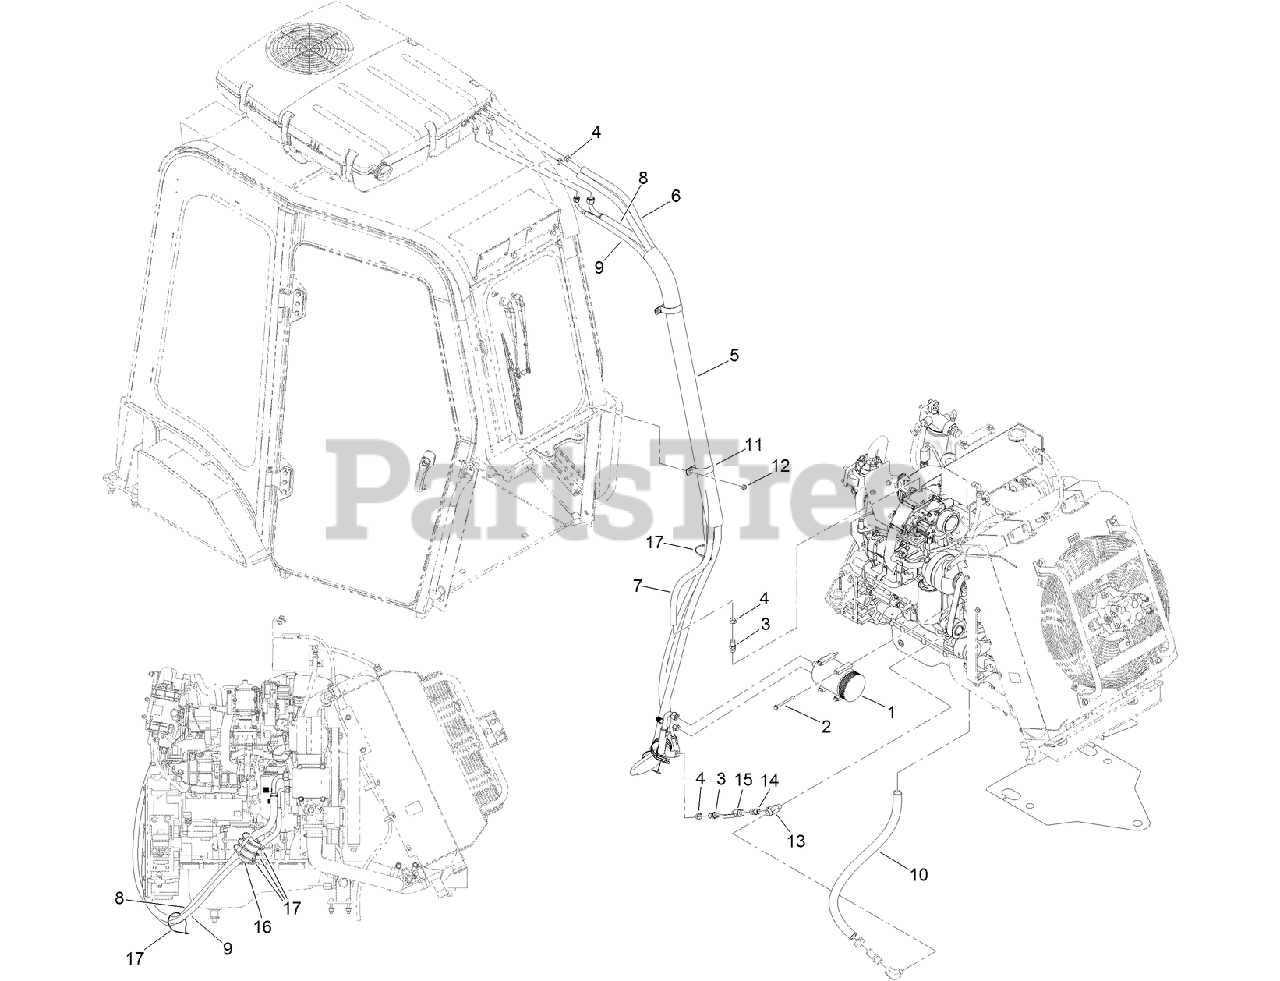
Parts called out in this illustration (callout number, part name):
1	COMPRESSOR-A/C
2	SCREW-HHF
3	FITTING-STRAIGHT
4	CLAMP-DRIVE, WORM
5	SLEEVE-PROTECTIVE
6	HOSE-HEATER
7	HOSE-HEATER
8	HOSE ASM
9	HOSE ASM
10	HOSE-COOLANT
11	CLAMP-SUPPORT
12	NUT-HF, NI
13	FITTING-TEE
14	COUPLING-PIPE, MALE
15	VALVE-BALL
16	PROTECTOR-HOSE
17	TIE-CABLE
